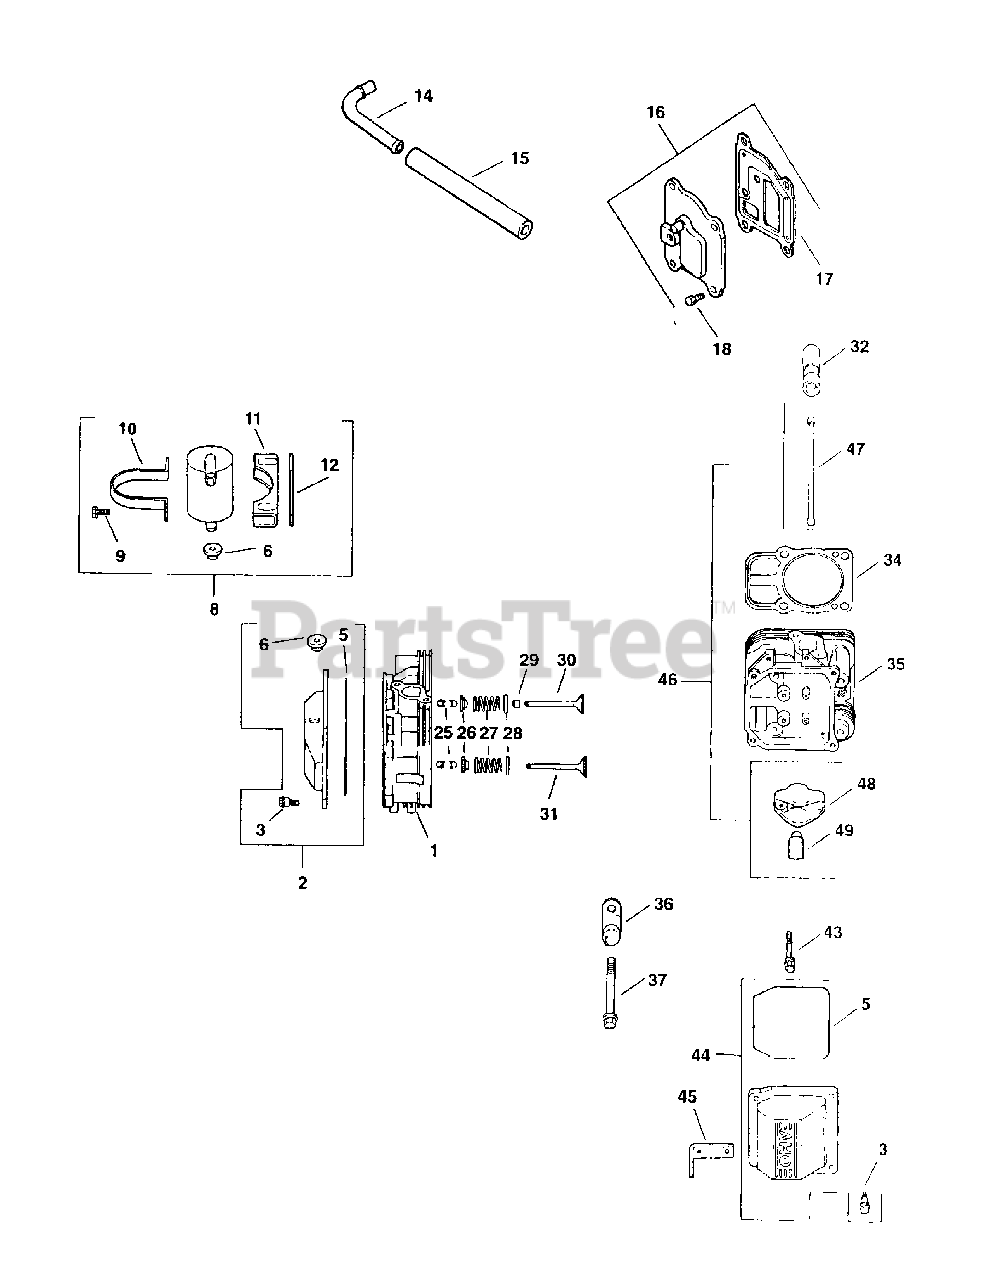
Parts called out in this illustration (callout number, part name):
1	Head Assembly, #1 Cylinder
2	Kit, Valve Cover-Breather
3	Screw, Hex Cap Shoulder
6	Grommet, Rubber
8	Kit, Breather Separator
9	Screw, Hex Flange
10	Strap, Breather
11	Bracket, Breather Separator
15	Hose, Breather
16	Kit, Breather Cover w/Gasket
16	Breather, Cover
17	Gasket, Breather
18	Screw, Hex Flange
25	Kit, Retainer
26	Cap, Valve Spring
27	Spring, Valve
28	Retainer, Spring
29	Seal, Valve Stem
30	Valve, Intake (Std.)
30	Valve, Intake (.25)
31	Valve, Exhaust (Std.)
31	Valve, Exhaust (.25)
32	Lifter, Valve
34	Gasket, Cylinder Head
35	Head Assembly, #2 Cylinder
37	Screw, Hex Flange
43	Screw, Hex Flange
44	Kit, Valve Cover-Plain
45	Strap, Lifting
46	Kit, Valve Train
47	Rod, Push
48	Arm, Rocker
49	Pivot, Cylindrical Rocker Arm
